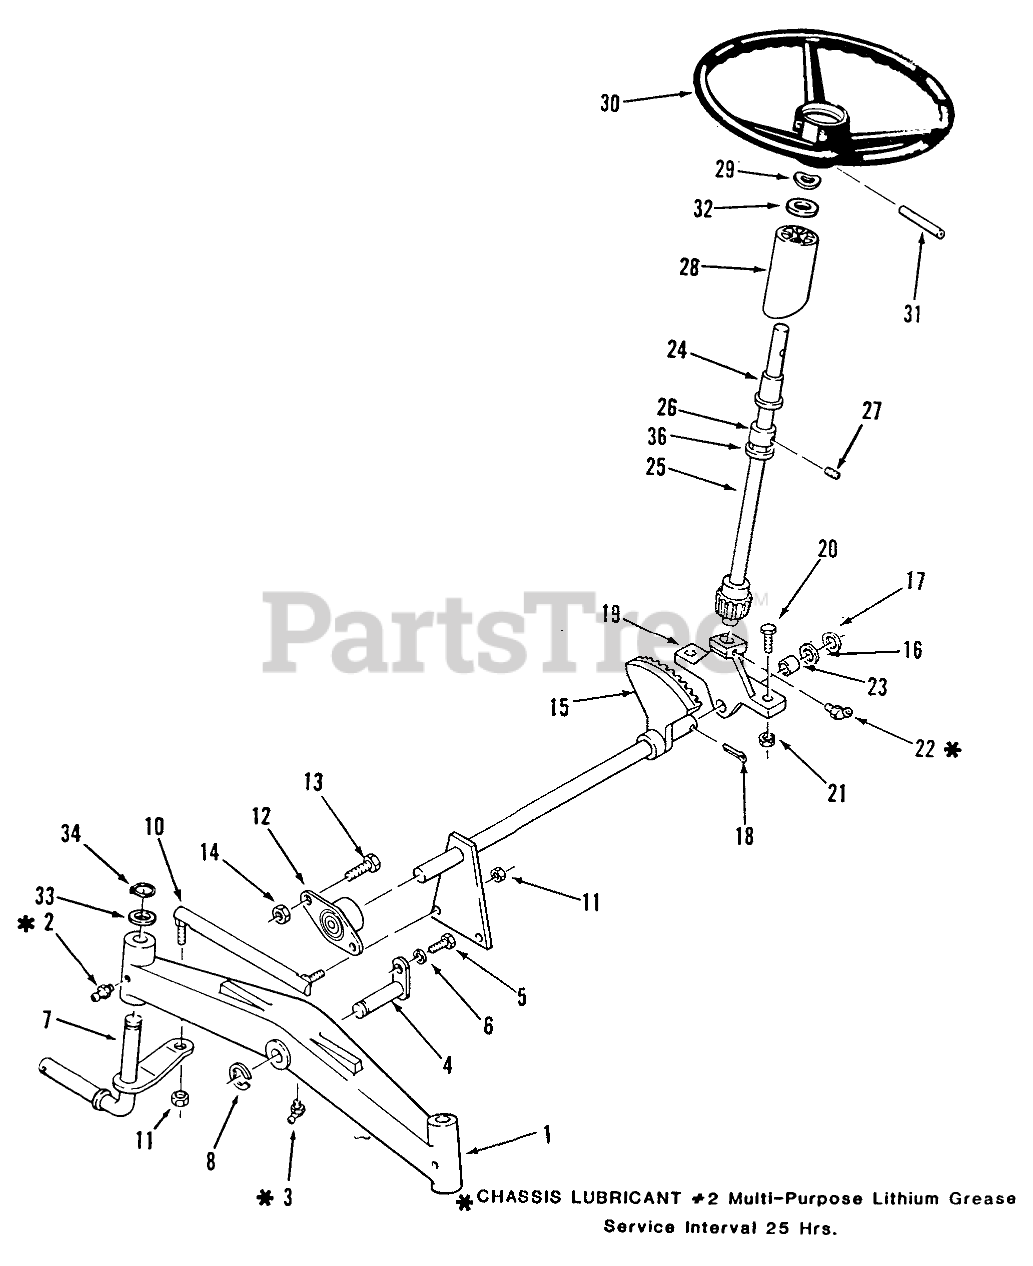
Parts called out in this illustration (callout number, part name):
1	AXLE-FRONT
2	Zerk
3	FITTING-GREASE
4	PIN AND PLATE ASM
5	H H C S
6	Lockwasher
7	RH SPINDLE WA
8	E-RING
10	Tie Rod RH
11	Nut
12	BEARING-FLANGED
13	BOLT
14	NUT
15	ASS'Y-STRG SHAFT R
16	WASHER-SHIM
17	WASHER
18	PIN-4
19	Support
20	Bolt
21	NUT
22	FITTING-GREASE
23	BEARING-BRONZE
24	BEARING-FLANGED
25	Shaft-Upper Steering
26	Collar
27	SCREW-SET
28	TUBE-STEERING
29	WASHER-BOWED
30	STEERING WHEEL-15"
31	Pin-Roll
32	WASHER-FLAT
33	WASHER
34	Snap Ring
36	RING-RETAINING
